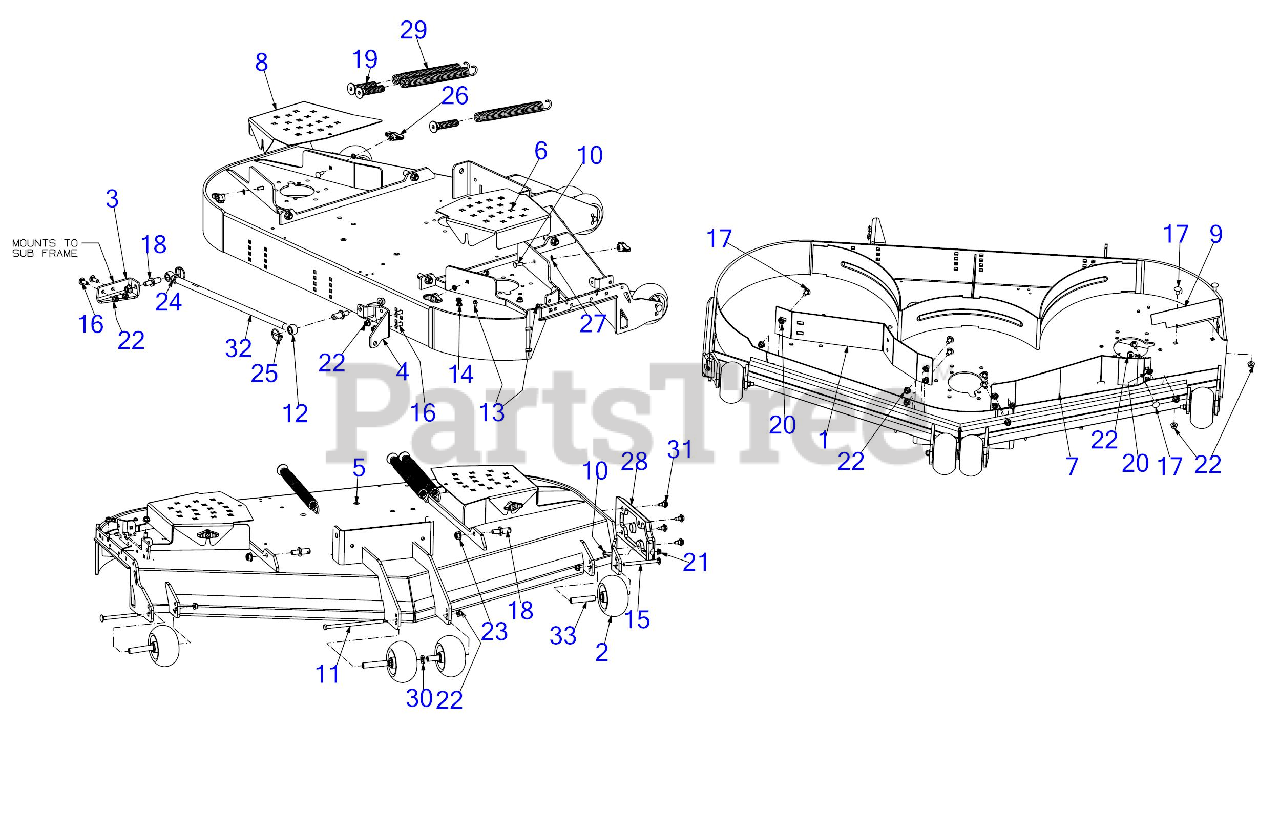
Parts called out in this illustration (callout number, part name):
2	5" DIA DECK WHEEL COMPLETE
10	CARRIAGE BOLT 5/16-18 x 1.00
11	SCREW 3/8-16 x 7.25 GR5
12	BOLT 5/8-16 x 2.63
13	SCREW 1/4-20 X.500
14	SCREW 5/16-18 x .500
15	CARRIAGE BOLT 3/8-16 x 4.25 GR5
16	CARRIAGE BOLT 3/8-16 x 1.00 GR5
17	CARRIAGE BOLT 3/8-16 x .75
19	SPRING INSERT SCREW
21	FLANGE LOCK NUT 5/16-18
24	HEX NUT
26	WING KNOB 5/16-18
28	DECK SKID PLATE (LH)
29	EXTENTION SPRING 1.20 x 11.35
30	FLAT WASHER .632X1.00X.16
31	SHOULDER SCREW .43X.29X5/16-18 TT
33	WHEEL SPACER .38ID x 3.04LG
